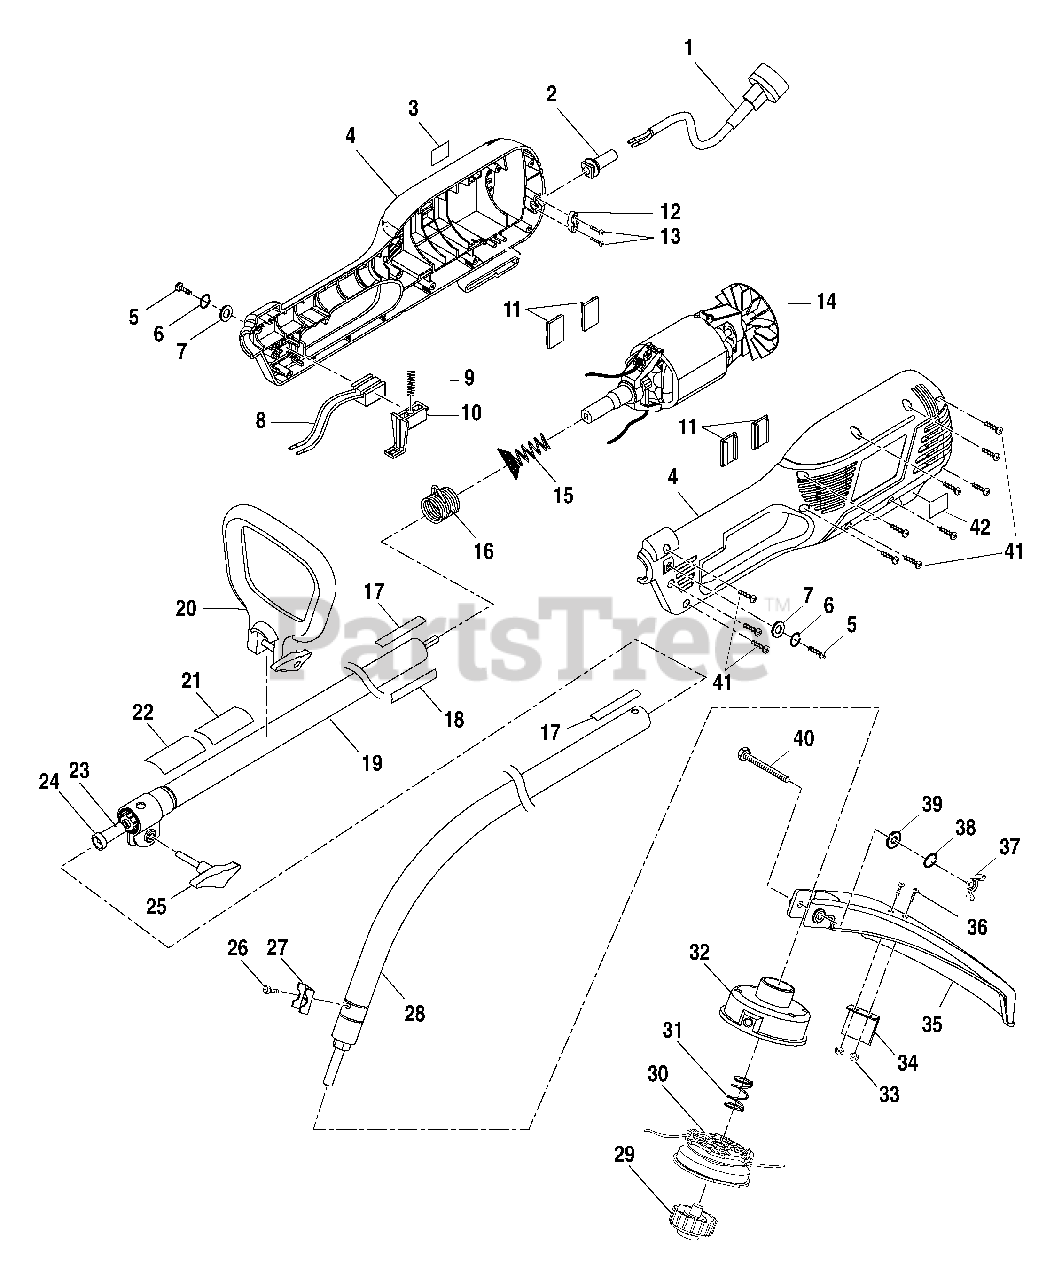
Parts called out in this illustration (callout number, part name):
1	POWER CORD
2	BEND RELIEF
3	LOGO PLATE HOUSING SUPPORT
4	HOUSING ASSEMBLY
5	SCREW (M4 X 12 mm)
6	SPRING WASHER (M4)
7	WASHER (M4)
10	SWITCH TRIGGER
11	RUBBER CUSHION
12	CORD CLAMP
13	SCREW (M42 X 15 mm)
14	MOTOR ASSEMBLY
17	ICON LABEL
18	DATA PLATE
19	ALUMINIUM BOOM ASSEMBLY
20	AUXILIARY HANDLE ASSEMBLY
21	WARNING LABEL
22	WARNING LABEL
23	SCREW (M4 X 4 mm)
25	CLAMP LOCK KNOB
26	SCREW (1024 X 3/8 in HEX HD)
27	GRASS DEFLECTOR CLAMP
28	D/SHAFT HOUSING ASSEMBLY
29	RETAINING CAP
30	SPOOL W/LINE (080 in)
31	COMPRESSION SPRING
32	TRIMMER HEAD W/EYELETS
33	HEX NUT (1024)
34	LINE CUTTING BLADE
35	GRASS DEFLECTOR
36	SCREW (1024 X 7/8 in HEX HD)
37	WING NUT
38	LOCK WASHER
39	FLAT WASHER
40	SCREW (1024 X 2 in HEX HD)
41	SCREW (M42 X 19 mm)
42	LOGO PLATE HOUSING COVER
